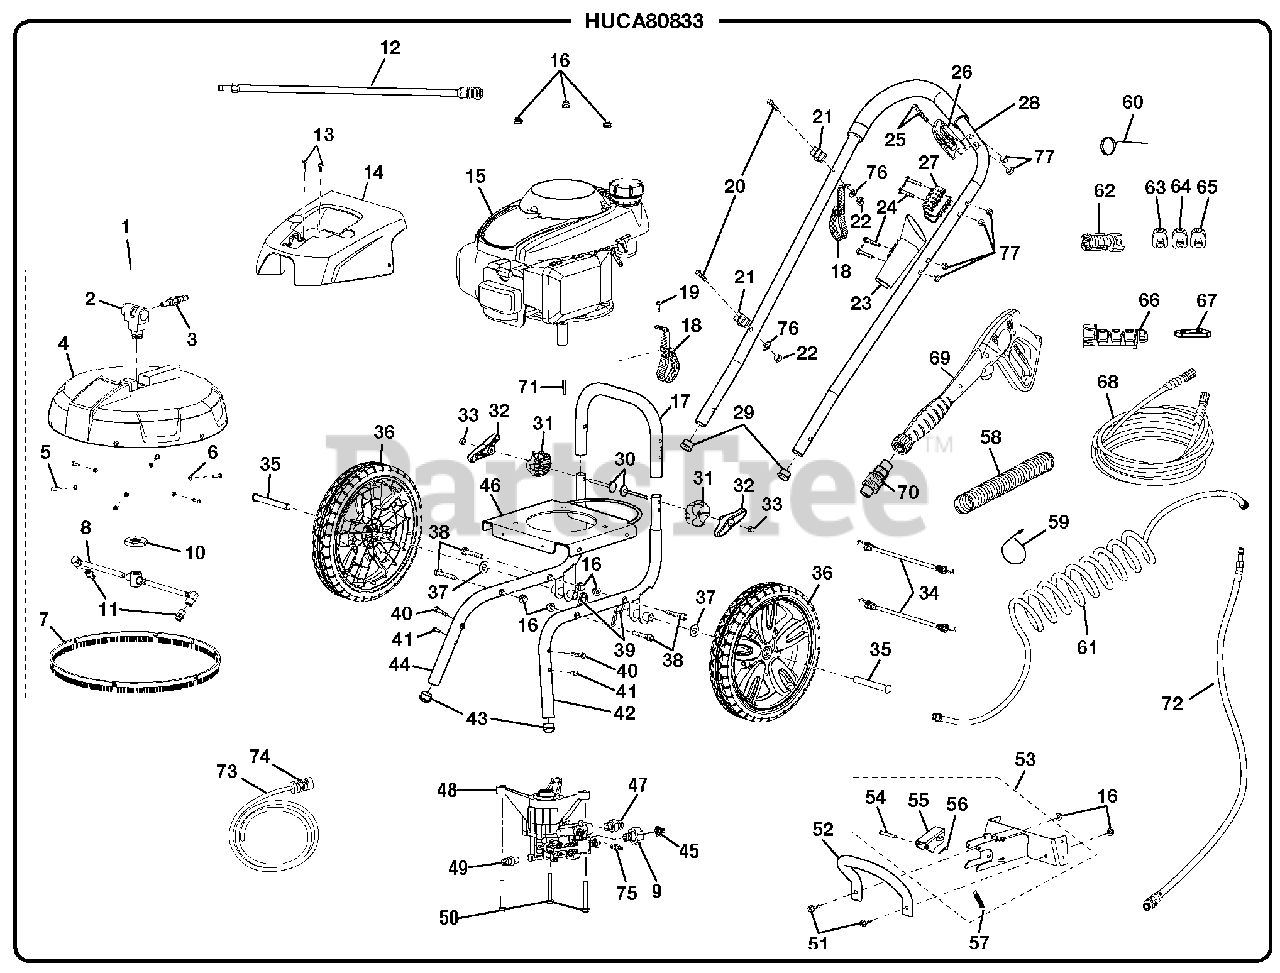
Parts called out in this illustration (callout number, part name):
1	Deck Assembly (Inc. Key Nos. 2-8, 10-11, 76-79 and 83)
2	Deck Pivot Assembly
3	1/8 Quick Connect (BSPP)
4	Deck w/Brush Assembly (Inc. Key Nos. 4-7, 76-79 and 83)
5	Bolt (M5 x 16 mm, Pan Hd.)
7	Deck Brush Skirt
8	Deck Wash Nozzle Assembly
9	Filter Screen
10	Nut (M22)
11	Nozzle w/015 Jet (1/4 NPT)
12	Wand Assembly
13	Screw (12-24)
14	Front Shroud Assembly (Inc. Key Nos. 80-82)
15	Honda Engine (See Honda Engine Manual)
16	Lock Nut (M8 x 1.25 mm)
17	Frame Connector Assemby (Inc. Key Nos. 18, 19)
18	Hose Storage Strap
19	Screw (12-14 x 1/2 in., Pan Hd.)
20	Bolt (M5 x 40 mm)
21	Spring Clip
22	Lock Nut (M5)
23	Lower Trigger Handle Holder
24	Screw (1/4-20 x 45 mm, Truss Hd.)
25	Screw (1/4-20 x 40 mm, Hex Hd.)
26	Trigger Handle Lock
27	Upper Trigger Handle Holder
28	Upper Handle Assembly (Inc. Key No. 29)
29	End Cap (25 mm)
30	Carriage Bolt (1/4-20 x 88.5 mm)
31	Handle Spacer
32	Knob Assembly
33	Acorn Nut (Centerlock)
34	Bungee Cord Assembly
35	Axle (D13.3 x 95)
36	Wheel (12 in. x 2 in.)
37	Washer (1/2 in.)
38	Hex Bolt (M8 x 50 mm)
39	Hitch Pin
40	Screw (1/4-20 x 37 mm, T-30 Torx Flat Hd.)
41	Screw (T-30 Torx, 1/4-20, Truss Hd. Shoulder)
42	Left Frame Assembly (Incl. Key No. 43)
43	Frame Glide
44	Right Frame Assembly (Incl. Key No. 43)
45	Lock Nut (1/4-20)
46	Engine Plate
47	Washer (D15 x d5.5 x 2t)
48	Pump (AR)
49	Thermal Relief Valve
50	Hex Bolt (M8 x 65 mm)
51	Hex Bolt (M8 x 20 mm)
52	Lift Handle
53	Deck Bracket Assembly (Inc. Key Nos. 54-57)
54	Connect Pin
55	Release Handle
56	Hitch Pin
57	Deck Lock Spring
58	Tube Conduit
60	Nozzle Cleaning Tool
61	15 ft. Self Coiling Garden Hose
62	Soap Blaster Nozzle Assembly
63	0deg Nozzle
64	15deg Nozzle
65	25deg Nozzle
66	Nozzle Holder
67	Spring Clip
68	Hose
69	Trigger Handle Assembly (Inc. Key Nos. 88-90)
70	Expand Style Quick Connect
71	Output Shaft Key
72	Deck High Pressure Hose Assembly
73	Injection Hose
75	Detergent Suction Kit
76	Washer (D15 x d5.5 x 2t)
77	Lock Nut (1/4-20)
